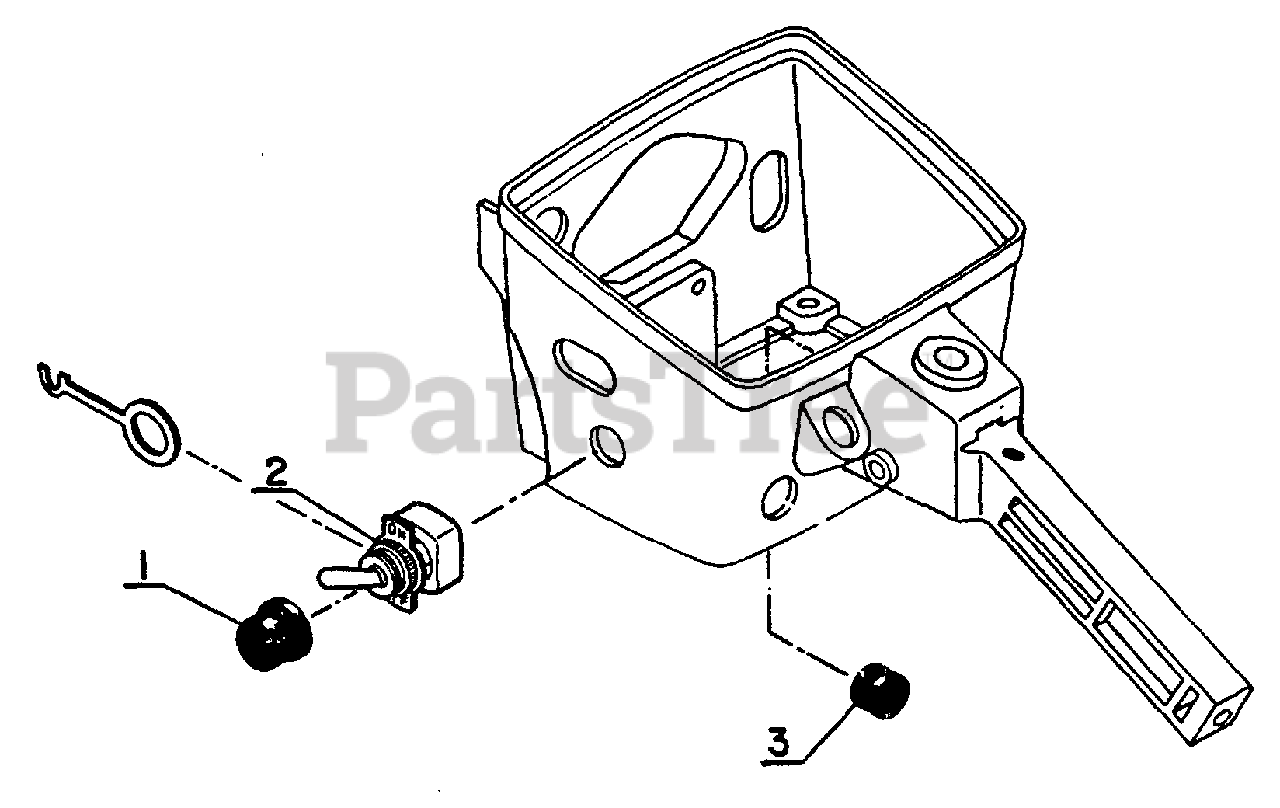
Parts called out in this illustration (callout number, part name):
1	CAP, RUBBER
2	SWITCH, STOP
3	RUBBER BUSH
